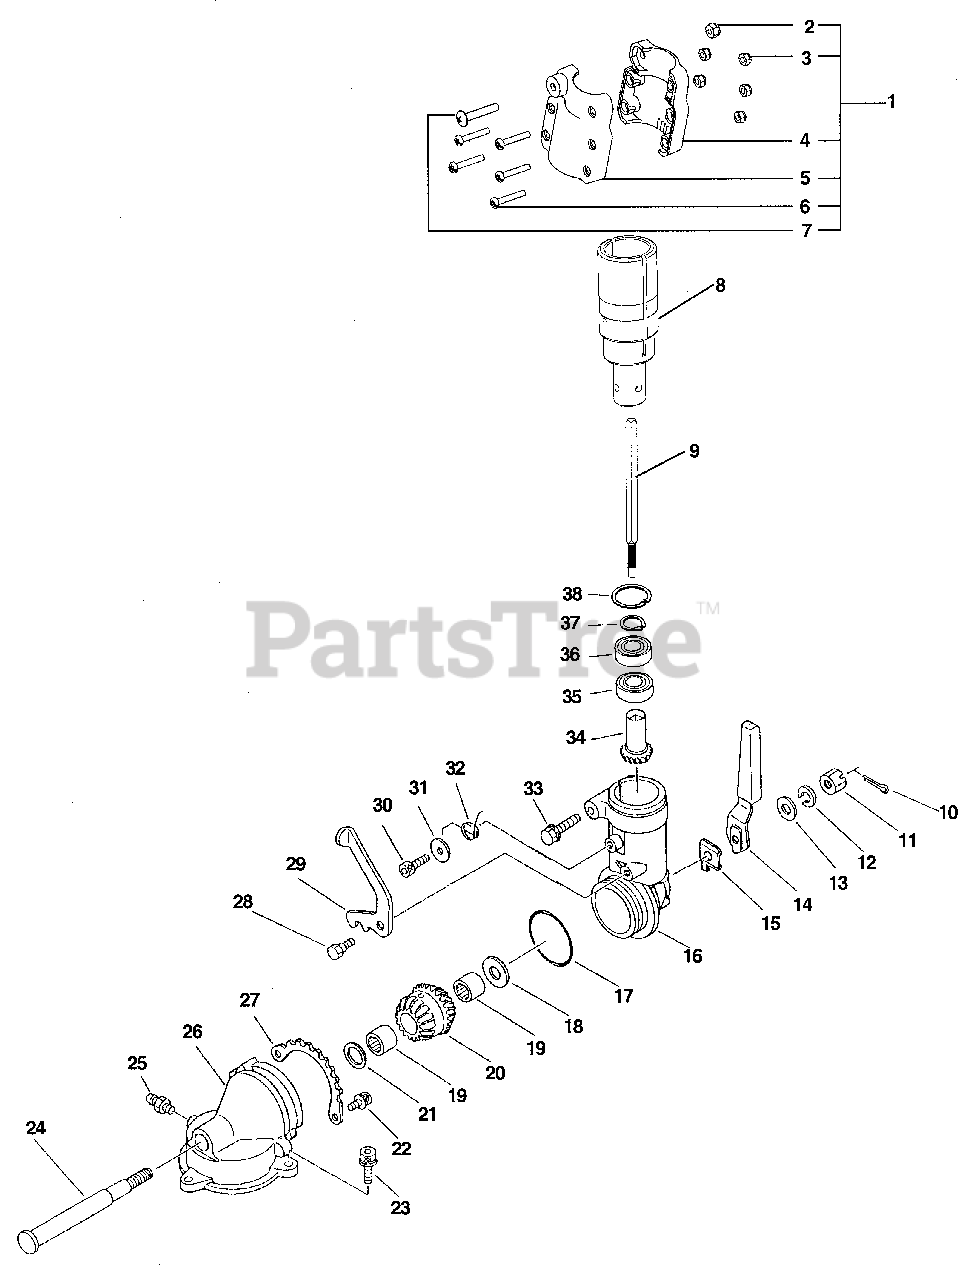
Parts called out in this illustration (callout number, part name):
1	CLAMP ASY, COMPRESSION
2	NUT, LOCKING
3	NUT, LOCK 10-24 UNC
4	COLLAR, LOWER
5	COLLAR, UPPER
6	SCREW, TORX 10-24 UNC 1-1/4
7	SCREW, TRUSS
8	CONNECTOR
9	SHAFT, PINION
10	PIN, COTTER 1.6×16
11	NUT, SLOT 6
12	WASHER, SPRING 6
15	PLATE, ANGLE
16	GEAR CASE
17	O-RING 32
18	WASHER, THRUST
19	BEARING, NEEDLE
20	GEAR, BEVEL
21	WASHER, ADJUSTMENT
22	BOLT 4×10
23	BOLT 5×18
24	SHAFT, GEAR
25	FITTING, GREASE
26	COVER, GEAR CASE
27	RESETTER, LATCH
30	BOLT 5×14
31	WASHER 5.5×12×0.8
32	SPRING, THROTTLE LOCKOUT
33	BOLT 5×35
34	GEAR, DRIVE
35	BEARING, BALL 6900
36	BEARING, BALL 6900-Z
37	RING, SNAP Ø10
38	RING, SNAP Ø22
39	SCREW 5×10
